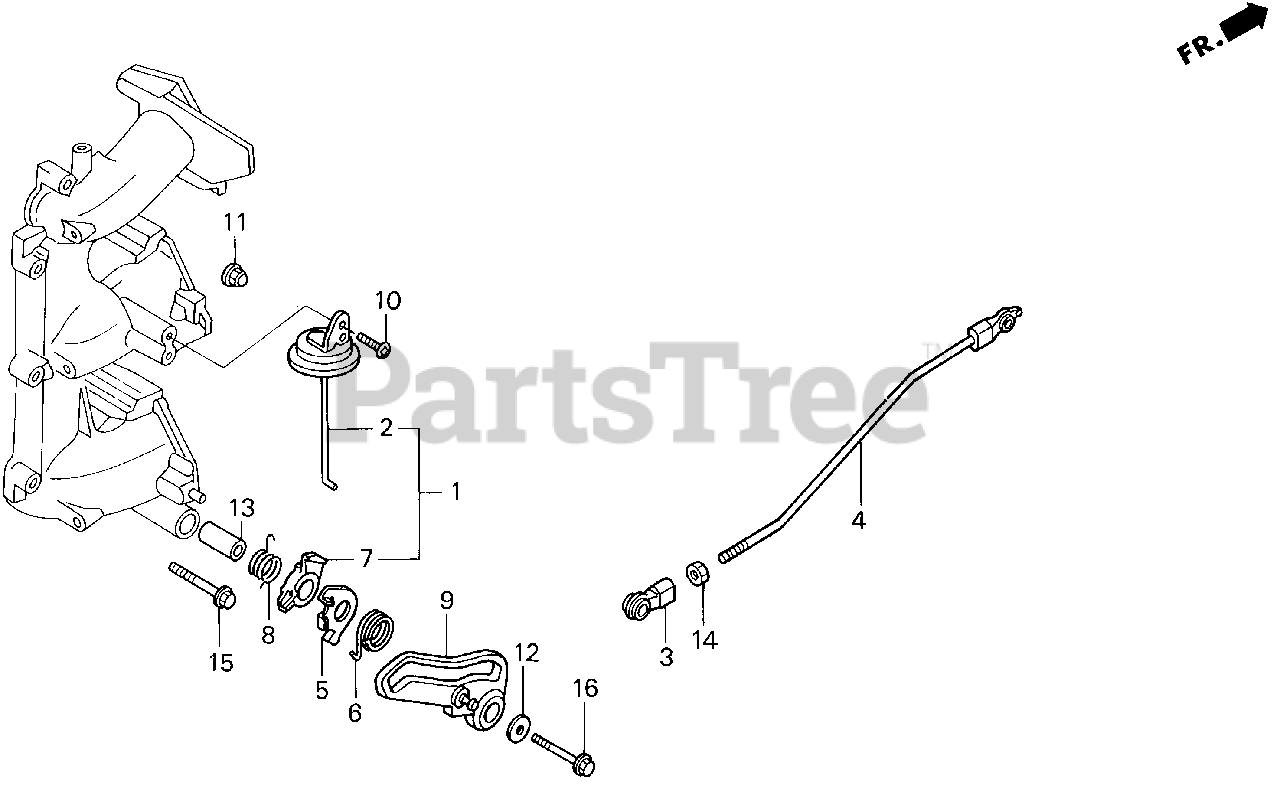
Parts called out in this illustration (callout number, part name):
2	DIAPHRAGM ASSY.
3	LINKAGE, PIVOT
4	ROD, THROTTLE
5	PLATE, ASSIST
6	SPRING, ASSIST
7	CAM, THROTTLE OPENER
8	SPRING, OPENER CAM RETURN
9	CAM, THROTTLE
10	BOLT, TORX (6X14)
11	NUT, CAP (6MM)
12	WASHER, PLAIN (6MM)
13	COLLAR (6.7X12.5X24)
14	NUT, HEX. (5MM)
15	BOLT, FLANGE (6X32)
16	BOLT, FLANGE (6X40)
